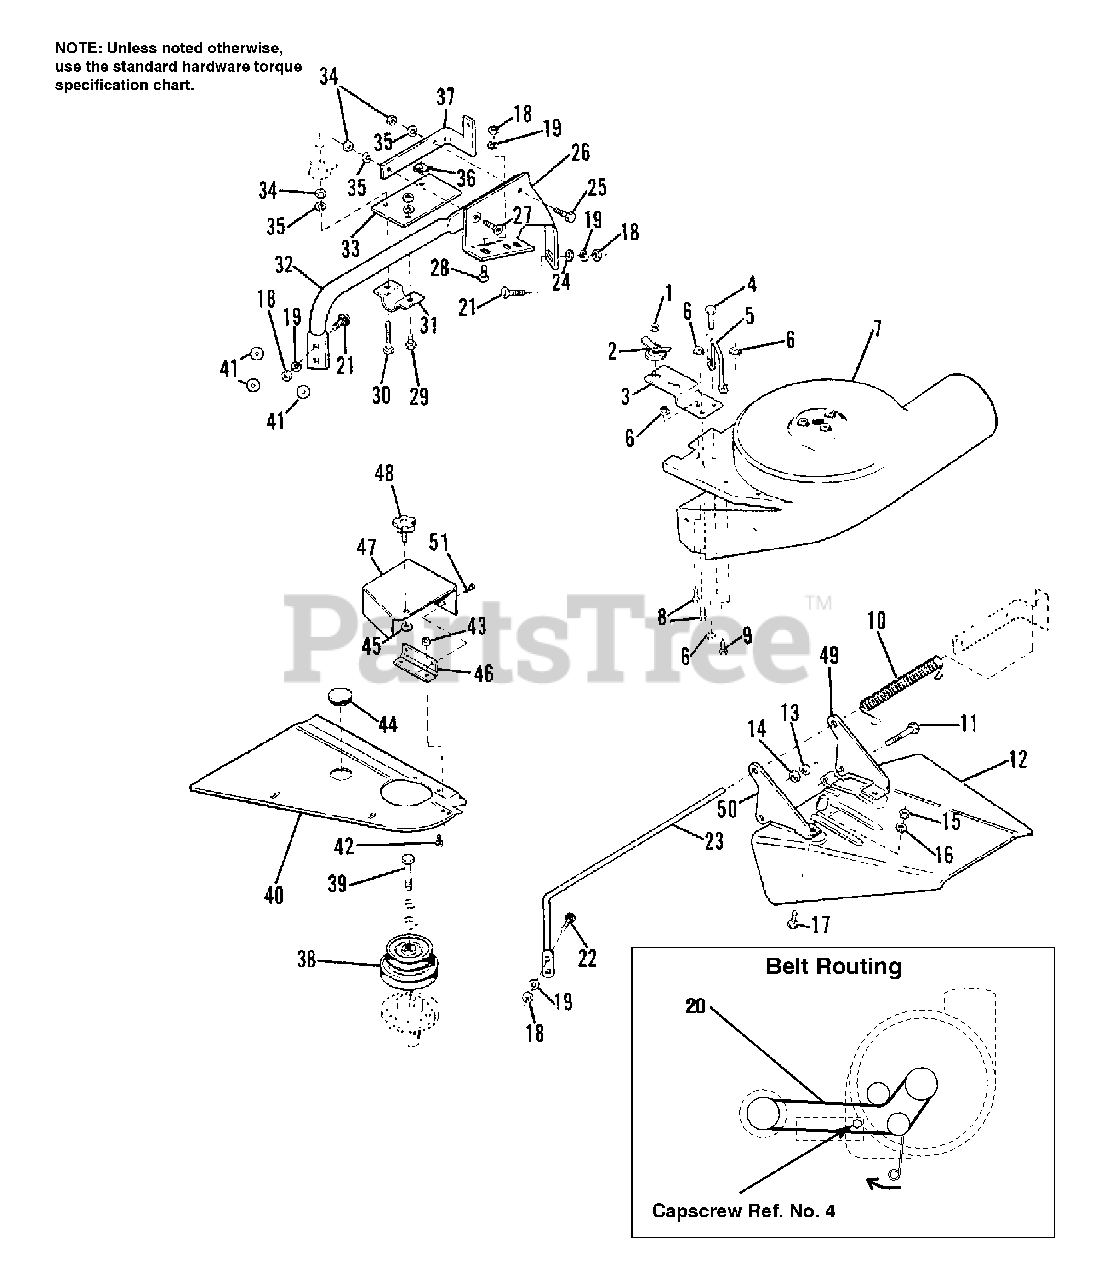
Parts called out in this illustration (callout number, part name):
1	NUT, Hex Lock, 5/16-18
2	NUT & CUP ASSEMBLY
3	PLATE, Mounting
4	CAPSCREW, Hex Hd,1/4-20 x 2-1/4
5	STOP, Deflector
6	NUT, Hex Flange Whiz Lock, 1/4-20
7	TURBO ASSEMBLY
8	CAPSCREW, Hex Hd, 1/4-20 x 3/4
9	CAPSCREW, Hex Hd, 1/4-20 x 7/8
10	SPRING, Torsion
11	CAPSCREW, Hex Hd, 7/16-14 x 2-3/4
12	DEFLECTOR ASSEMBLY (From Mower)
13	WASHER, Lock, 7/16
14	NUT, Hex, 7/16-14
15	NUT, Hex, 5/16-18
16	WASHER, Lock, 5/16
17	CAPSCREW, Hex Hd, 5/16-18 x 7/8
18	NUT, Hex, 3/8-16
19	WASHER, Lock, 3/8
20	V-BELT
21	CARRIAGE BOLT, 3/8-16 x 1
22	CAPSCREW, Hex Washer Hd, Taptite, 5/16-18 X 1
24	WASHER, 3/8
25	CAPSCREW, Hex Hd, 5/16-18 x 1-1/4
26	BRACKET, Support
27	SCREW, Flat Hd, Hex Socket, 5/16-18 x 1-1/4
28	CAPSCREW, Hex Hd, 3/8-16 x 1
29	CAPSCREW, Hex Hd, 5/16-18 x 5/8
30	CAPSCREW, Hex Hd, 5/16-18 x 2-1/2
31	CLAMP, Lower
32	BRACE, Bracket Support
33	CLAMP, Upper
34	NUT, Hex, 5/16-18
35	WASHER, Lock, 5/16
36	NUT, Speed, 5/16-18
37	PIVOT ASSEMBLY, Deflector
38	PULLEY ASSEMBLY
39	CAPSCREW, Hex Hd, 7/16-14 x 2-1/4
40	COVER, LH Mower
42	SCREW, Rd Hd Machine, #10-32 x 3/8
43	NUT, Hex Flange, #10-32
44	PLUG, Mower Cover
45	NUT, Push, 5/16
47	COVER, Belt
48	KNOB, Plastic
49	BRACKET, RH Pivot
50	BRACKET, LH Pivot
51	POP-RIVET, 3/16 x 5/16
